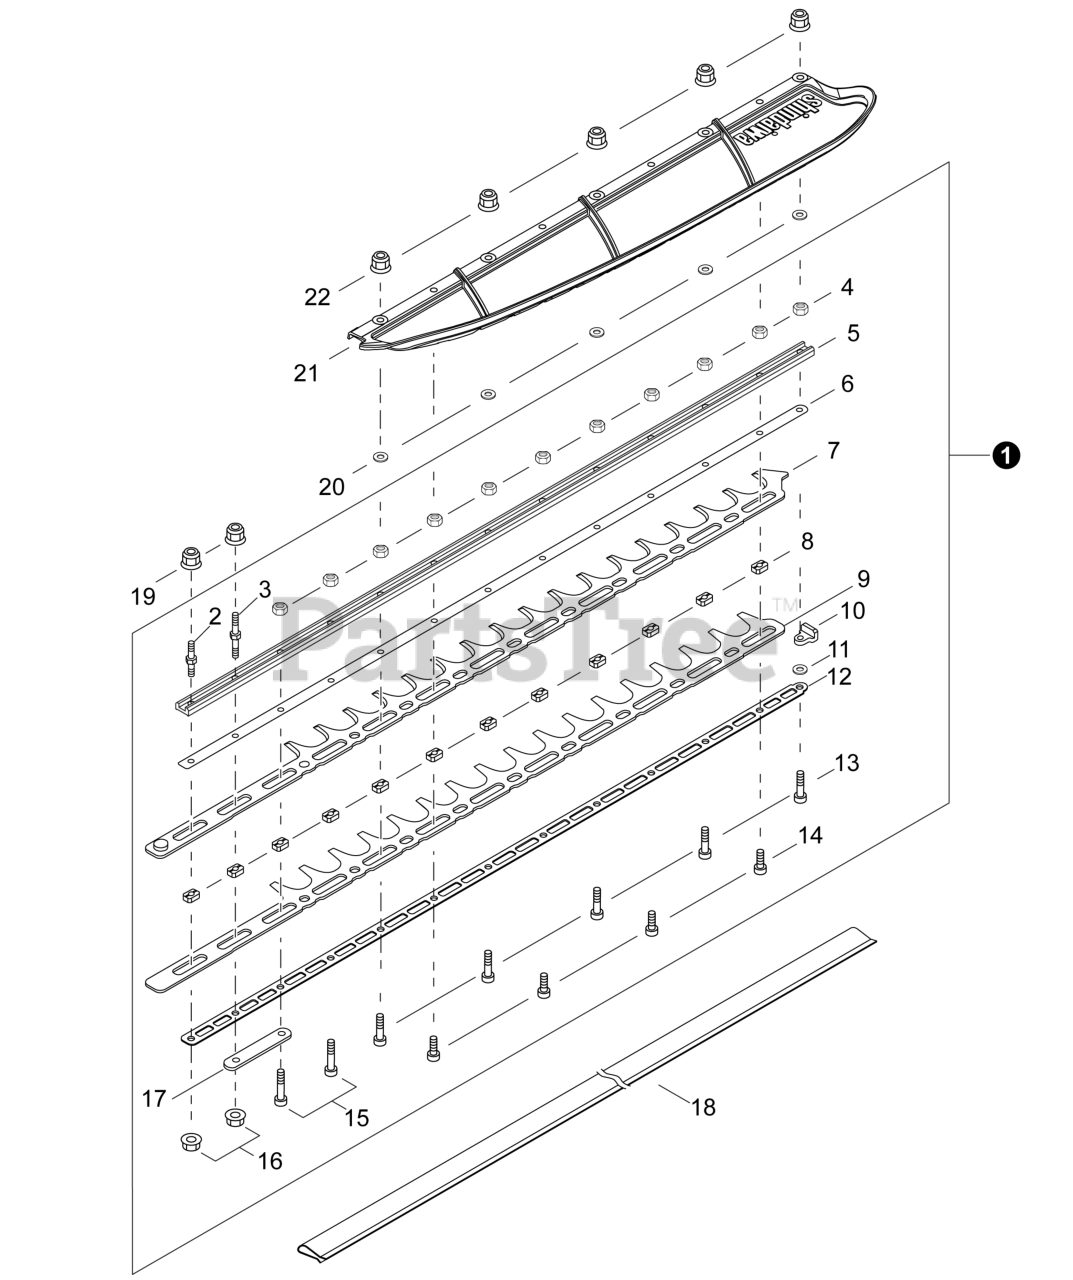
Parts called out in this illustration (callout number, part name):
1	CUTTER ASSY, 37.6"
2	STUD, MOUNTING M5×36
3	STUD, MOUNTING M5×44
5	SUPPORT, BLADE 37.6"
6	SUPPORT, BLADE 37.6"
7	BLADE - UPPER - 37.6"
9	BLADE - LOWER - 37.6"
12	SUPPORT, BLADE 37.6"
13	BOLT, TORX 5×25
14	BOLT, TORX 5×16
15	BOLT, TORX 5×30
16	NUT, FLANGE M5
17	PLATE, EYE
18	SCABBARD
19	NUT, FLANGE M5
20	WASHER, FLAT 5.5×10×0.8
21	DEFLECTOR, DEBRIS
22	NUT, FLANGE M5
